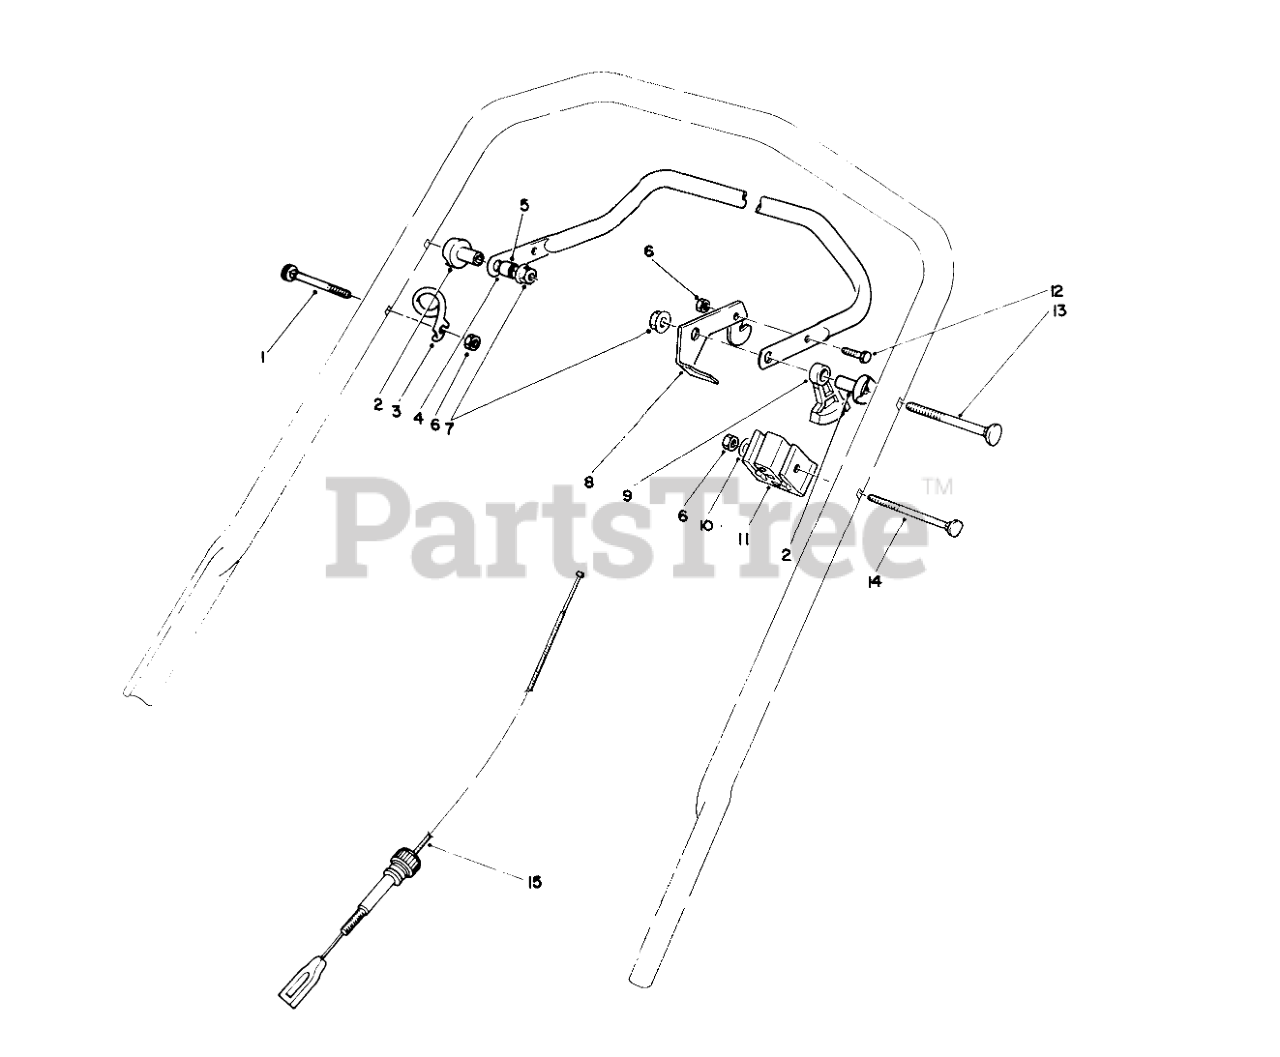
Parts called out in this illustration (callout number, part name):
1	HANDLE SCREW
2	SPACER-SUPPORT
3	Guide
4	Bar-Control
5	SPACER-NYLON
6	NUT-LOCK, NI
7	NUT-LOCK, NI
8	LEVER-CONTROL
9	LEVER-TRACTION
10	WASHER-FLAT
11	SUPPORT-CABLE
12	SCREW-HH
13	5/16-18 X 2 HNDLE SCREW
14	HANDLE SCREW
15	CABLE-TRACTION
